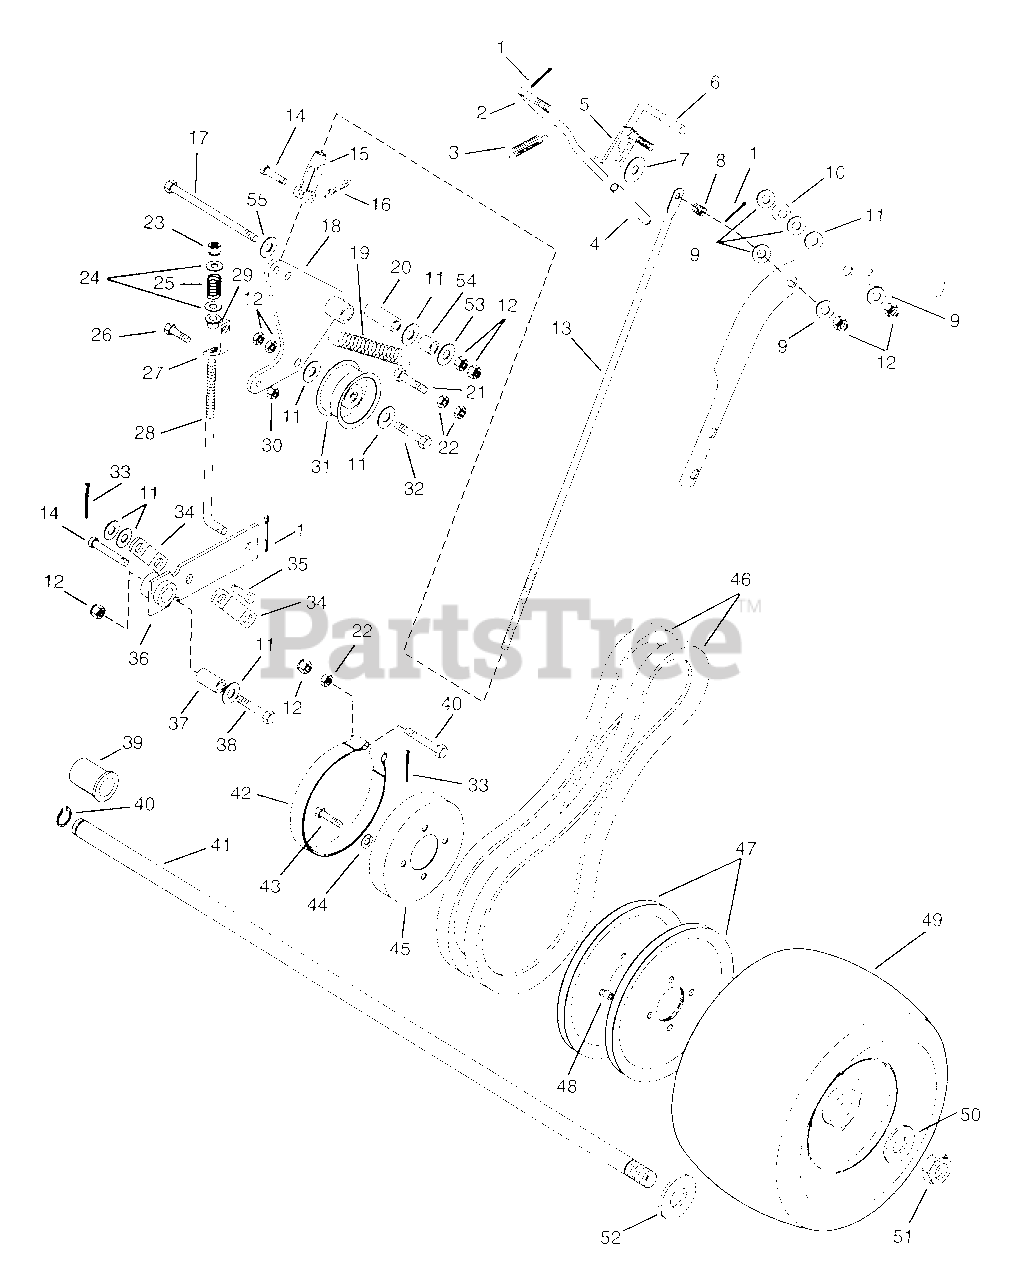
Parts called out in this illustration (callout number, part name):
1	Pin-Cotter .09 x .75
2	Lever-Hand Control
3	Spring-Tension .041 x .500 x 1.750
4	Grip-Hand Clutch Lever
5	Weldment-Clutch-Brake Lock
6	Tip-Brake Lock Lever
7	Washer-Flat-Steel .4 x 1.375
8	Spring-Compression .045 x .600 x .750
9	Washer-Flat-Nylon .375 x .75 x .060
10	Spring Washer
11	Washer-Flat-Steel .406 x .812 x .065
12	Nut-Locking-Center .38-16
13	Rod-Clutch Actuating
14	Pin-Clevis .38 x 1.25
15	Clevis .38-24 Adjustable
16	Pin-Hair Internal .08 x .18 x 1.18
17	Bolt-Hex .38-16 x 4.00 Grade 5
18	Weldment-Wheel Clutch Arm
19	Spring-Tension .069 x .62 x 3.50
20	Bushing-Sleeve .385 x .610 x 1.80
21	Bolt-Hex .38-16 x 1.50 Grade 5
22	Nut-Hex .31-18
23	Nut-Locking-Center .31-18
24	Washer-Flat-Steel .344 x .688 x .065
25	Spring-Compression .125 x .78 x 1.00
26	Bolt-Hex .25-20 x .75 Grade 5
27	Left-Bracket-Pro Brake Link
28	Rod-Brake
29	Bushing-Flange .320 x .620 x .312
30	Nut-Locking-Center .25-20
31	Sheave 3.25 x 1.25
32	Bolt-Hex .31-18 x 2.25
33	Pin-Cotter .12 x .75 Extprsqct
34	Link-Brake Arm
35	Pin-Clevis .38 x .75
36	Weldment-Brake Arm
37	Bushing-Sleeve .391 x .622 x .950
38	Bolt-Hex .38-16 x 2.00 Grade 5
39	Bushing-Flange 1.010 x 1.38 x 1.4 x 1.65
40	Ring-Retaining-External .906 x .078
41	Axle Shaft-Pro-150
42	Assembly-Brake Band-Pro
43	Bolt-Hex .31-18 x 1.50 Grade 5
44	Washer-Lock .31 x .078
45	Drum-Brake
46	Drive Belt-Matched Pair
47	Pulley-V 9.00 x 3.75
48	Bushing-Sleeve .385 x .625 x .475
49	Assembly-Wheel, 13 x 6.00-6
50	Washer-Flat-Steel 1.010 x 1.505 x .062
51	Nut-Locking-Center .44-14
52	Washer-Thrust 1.55 x 1.002 x .093
53	Washer-Flat-Steel .38 x .87 x .179
54	Bushing
55	Washer-Flat-Steel .44 x 1.625 x .315
